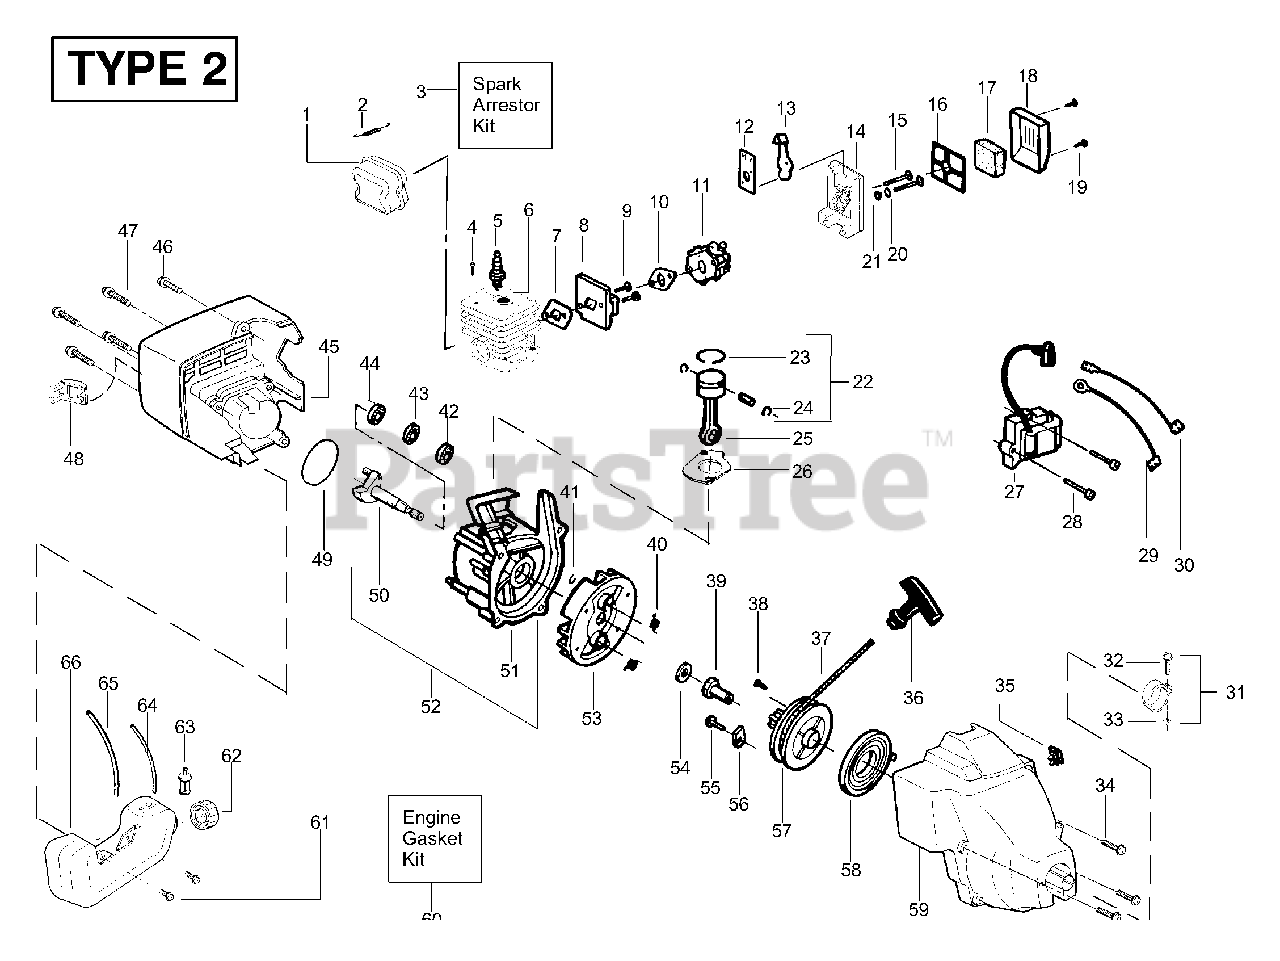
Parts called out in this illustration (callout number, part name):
1	Kit-Muffler S.A.
2	Muffler Spring
3	Kit-Spark Arrestor
4	Screw-Cylinder
5	Spark Plug (RCJ-6Y)
6	Kit-Cylinder
7	Gasket-Cyl./Carb. (kit)
8	Carb. Adaptor
10	Gasket-Carb. (kit)
11	Kit-Carb. (WA-226)
11	Kit-Carb. (C1U-W7)
11	Kit-Carb. (C1U-W7D)
12	Choke Plate Mounting
13	Choke Shutter
16	Plate-Filter Support
17	Air Filter Foam
18	Air Filter Cover
20	Spacer-Choke
22	Kit-Piston
23	Piston Ring
24	Piston Pin Retainer
25	Connecting Rod Ass'y.
26	Gasket-Cylinder (kit)
27	Ignition Module
29	Assy-Ground Wire
30	Assy-Leadwire
31	Nose Cone Clamp Ass'y.
32	Screw-Nose Cone
33	Nut-Nose Cone
34	Screw
35	Kit-On/Off Switch
36	Starter Handle
37	Kit-Rope
39	Drive Coupling
40	Starter Dog Spring
41	Retain. Ring-C'shaft
42	Outer Bearing
43	Kit-C'case Seal
44	Inner Bearing
47	Screw
48	Guard-Muffler
49	O-Ring-C'case (kit)
50	Assy-Crankshaft
51	Kit-Crankcase Ass'y.
52	C'case & C'shaft Assy.
53	Flywheel Ass'y.
54	Washer-Flat
56	Retainer-Can
57	Starter Pulley Kit
58	Starter Spring
59	Kit-Fan Hsg/Shroud
60	Kit-Engine Gasket
61	Retainer
62	Assy-Fuel Cap
63	Assy-Fuel Pickup
64	Kit-Fuel Line (Small)
65	Kit-Fuel Line (Large
66	Assy-Fuel Tank
